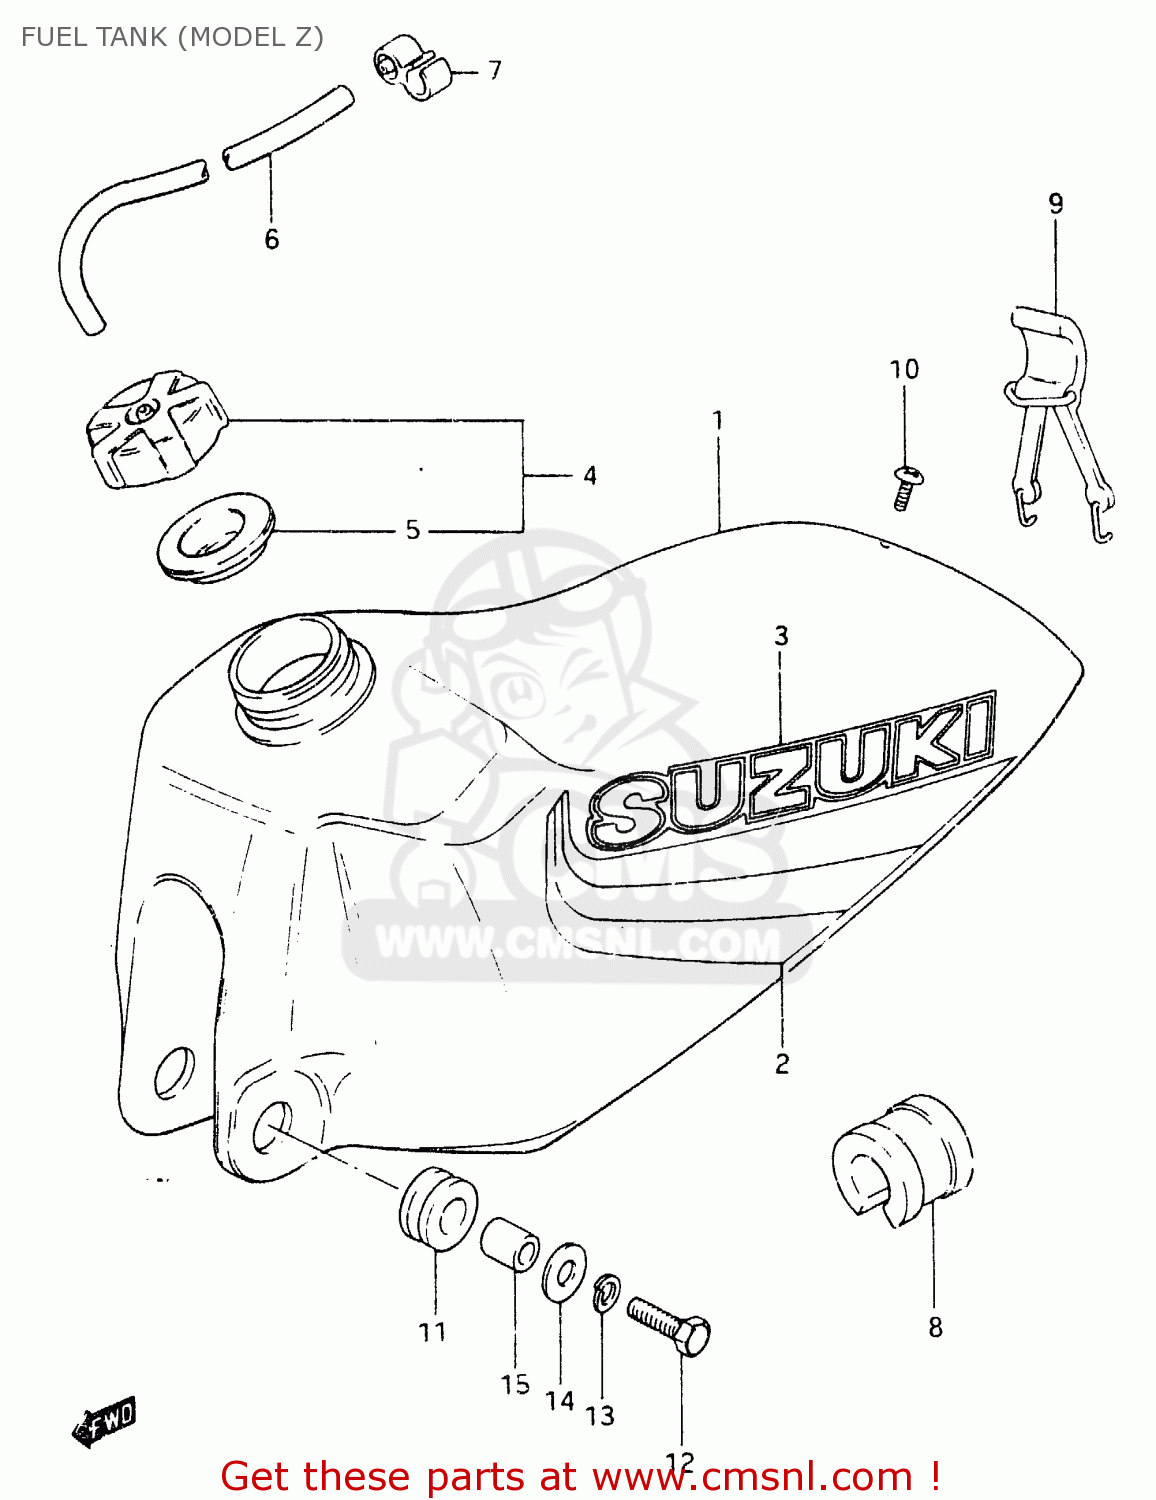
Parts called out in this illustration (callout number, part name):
1	TANK ASSEMBLY,FUEL
2	TAPE SET,FUEL TANK
3	EMBLEM
4	CAP,FUEL TANK FILLER
5	GASKET,FUEL TANK CAP (NAS)
6	HOSE
7	CLAMP,BREATHER HOSE
8	CUSHION,FUEL TANK UPR
9	BAND,FUEL TANK,REAR
10	SCREW (6X15)
11	CUSHION
12	BOLT
13	LOCK WASHER
14	WASHER
15	SPACER (8.8X12X13.5)
